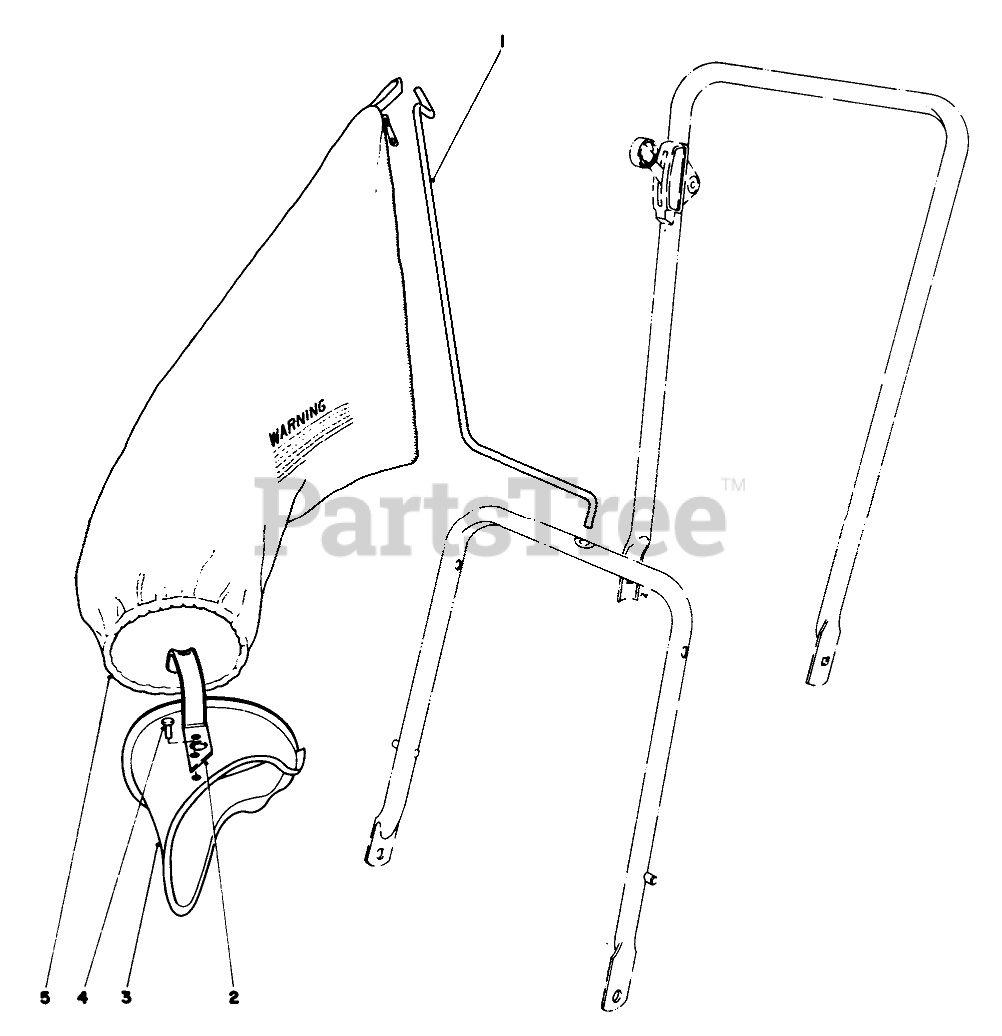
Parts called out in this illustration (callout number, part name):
1	BAG HANGER ROD
2	BAG CHUTE HANDLE
3	Grass Chute Assembly (Incl. Ref. #2 & 4)
4	RIVET 3/16 X 7/16
5	Grass Bag Assembly
